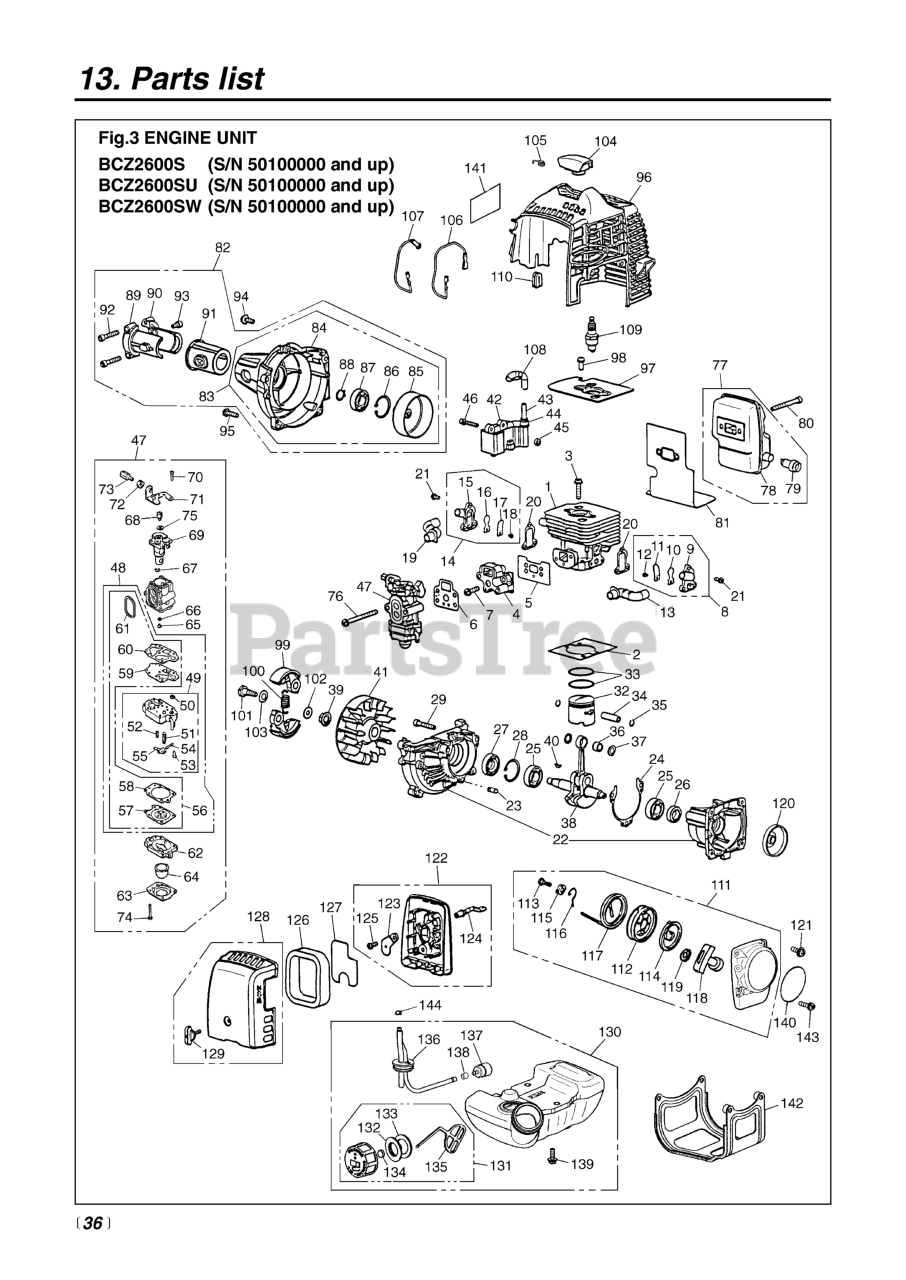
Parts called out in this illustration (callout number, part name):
1	CYLINDER (RPLS -12110)
2	GASKET, BASE
3	BOLT, M5 X 22
4	INSULATOR (RPLS. -13160/13161)
5	GASKET, INSULATOR
6	GASKET, CARBURETOR
7	SCREW, M5X20 (RPLS.1400-75510)
8	REED VALVE (RPLS 4810-16100)
9	VALVECASE
10	VALVE, REED
11	STOPPER
12	SCREW, M3 x 8
13	PIPE, AIR
15	VALVE CASE (F) (RP.4810-16210)
16	VALVE, REED
17	STOPPER
18	SCREW, M3 x 8
19	PIPE, AIR (F)
20	GASKET, VALVE
21	SCREW
22	CRANKCASE-C
23	PIN
24	GASKET
25	BEARING
26	SEAL
27	SEAL, OIL (RPLS 1140-21220)
28	RING, SNAP, M28 x 1.2
29	BOLT, M5 X 30
32	PISTON
33	RING, PISTON
34	PIN, PISTON
35	RING, SNAP (RPLS 1101-41320)
36	BEARING (RPLS 1140-41330)
37	WASHER
38	CRANKSHAFT COMPLETE
40	KEY
41	ROTOR
42	COIL-A
43	CORD
44	CAP
45	SPACER (RPLS -71260)
46	BOLT, M4 x 22
47	CARBURETOR (WYA-1-1)
48	REBUILD KIT
49	BODY-A
50	SCREEN
51	VALVE
52	SPRING
53	SCREW
54	PIN
55	LEVER
56	KIT, GASKET (REPLACES-06020)
57	DIAPHRAGM
58	GASKET, DIAPHRAGM
59	DIAPHRAGM, PUMP
60	GASKET, PUMP
61	RING
62	BODY, PURGE
63	COVER, PUMP
64	PUMP, PRIMING
65	JET (USE -81251)
66	RING, O
67	RING
68	SWIVEL
69	VALVE
70	SCREW
72	NUT, CABLE ADJUSTER
73	SCREW, CABLE ADJUSTER
74	SCREW
75	WASHER
76	SCREW, M5 x 60
77	MUFFLER ASSEMBLY
78	MUFFLER (REPLACES -15110)
79	ARRESTER
80	BOLT, M5 x 50
81	GASKET (RPLS T1501-15210)
82	COVER-A (USE -31002)
83	COVER-C (USE -31102)
84	COVER, FAN (REPLACES -31110)
85	DRUM (REPLACES 4810-31122)
86	RING, SNAP, M28 x 1.2
87	BEARING
88	RING, SNAP (RPLS 3130-13270)
89	BRACKET (A) (RPLS -31210)
90	BRACKET (B) (REPLACES -31220)
91	CUSHION
92	BOLT, M5 X 30
93	BOLT (USE 3310-31720)
94	SCREW
95	SCREW, M5X20 (RPLS.1400-75510)
96	COVER, ENGINE (RPLS -32110)
97	PLATE, CYLINDER
98	SCREW, M5 X 10
99	SHOE
100	SPRING
101	BOLT
102	WASHER, FLAT (USE 182303)
103	WASHER (RPLS -51241)
104	CAP (RPLS 4810-72110)
105	SPRING
106	CORD (BLACK)
107	CORD, EARTH (RED)
108	TUBE
110	GROMMET
111	RECOIL ASSEMBLY
112	REEL
113	SCREW
114	SPRING, SPIRAL
115	COLLAR
116	ARM
117	ROPE (REPLACES 4500-75160)
118	KNOB (RPLS -75420)
119	PLATE, STOPPER
120	PULLEY
121	SCREW
122	BODY ASSEMBLY
123	PLATE, CHOKE
124	LEVER, CHOKE
125	SCREW
126	ELEMENT
127	SCREEN
128	COVER ASSEMBLY
129	KNOB (RPLS -82220)
130	TANK ASSY (RPLS-85001)
131	CAP ASSY (RPLS -85201)
132	HOLDER (REPLACES -85230)
133	PACKING
134	FILTER
135	STOPPER
136	PIPE COMPLETE
137	FILTER ASSY
139	SCREW
140	LABEL, RECOIL
141	LABEL, COVER
142	GUARD (RPLS 4810-31911)
143	SCREW, M5 x 25
144	CLIP
